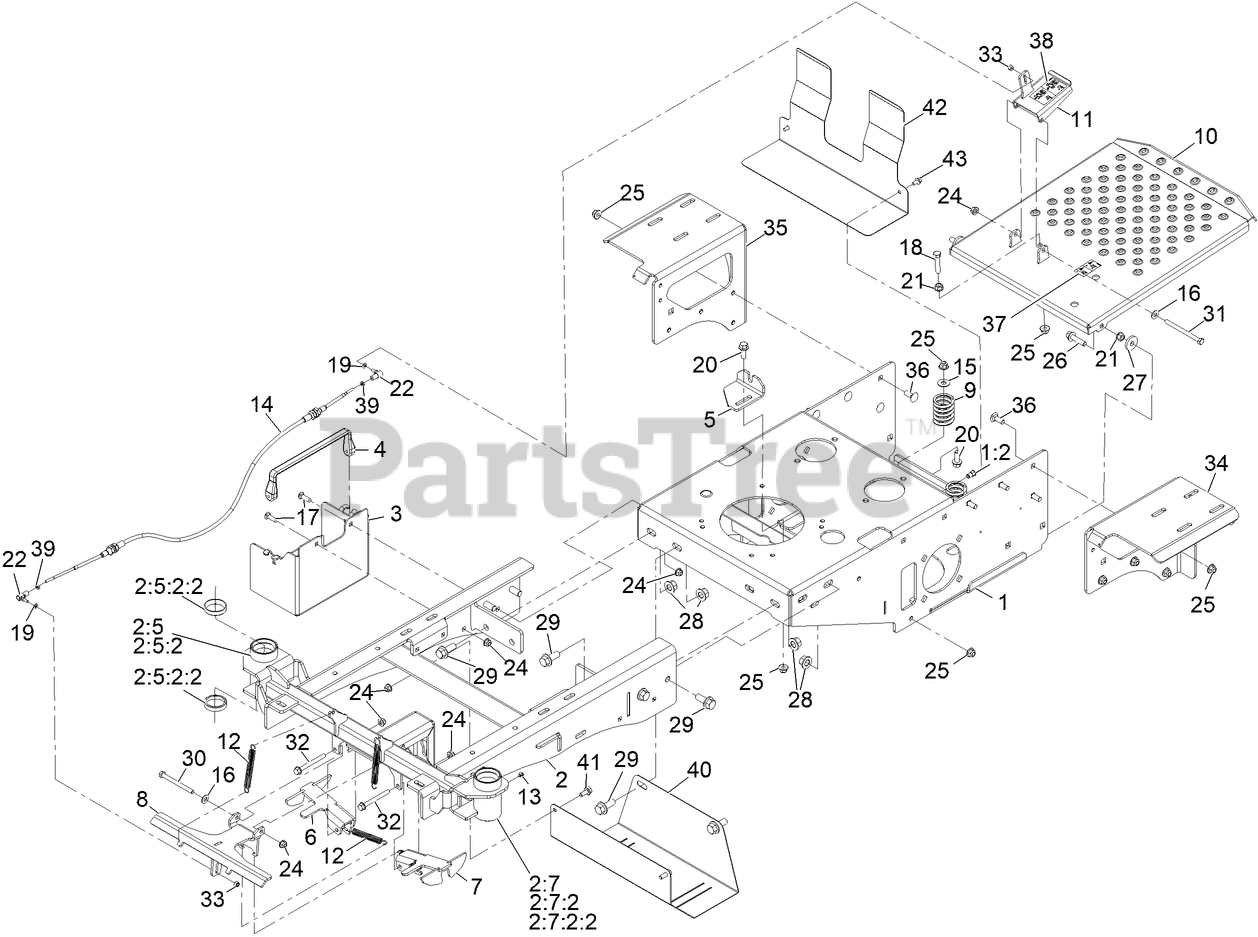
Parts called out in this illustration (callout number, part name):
1	FRAME-REAR
1:2	NUT-CLINCH,HEX
2	WLD, FRONT FRAME, JR36 24
2:5	Tube-Caster Rt
2:5:2	Tube-Caster, W/Cup
2:5:2:2	BEARING-CUP, TAPERED
2:7	Tube-Caster Lt
2:7:2	Tube-Caster, W/Cup
2:7:2:2	BEARING-CUP, TAPERED
3	BOX-BATTERY
4	BUNGEE (TARP STRAP)
5	Bracket, Lower Cable
6	Wing-Capture, Rt
7	Wing-Capture, Lt
8	WLD, CAPTURE, T-BAR, JR36
9	SPRING-COMPRESSION
10	WLD, FOOT PLATE, JR36
11	Wld, Foot Pedal, Lcs
12	SPRING-EXTENSION
13	FITTING-GREASE, ZERK
14	CABLE-CASTER, LOCKING
15	WASHER-FLAT
17	Bolt,Carriage,5/16-18X1,ST/ST 18-8
18	Screw-HH
19	WASHER-FLAT
20	SCREW-HHF
21	Nut-Hex Flange
22	BALL JOINT-SS
24	Nut-Hex Flange
25	Nut-Hex Flange
26	SCREW-HHF
28	NUT-HEX FLANGE
29	SCREW-HHF
30	SCREW-HH
31	Screw-HH
32	SCREW-HHF
33	Nut,NYL Lock,#10-32,ST/ST 18-8
34	WLD, MOUNT, FERT BOX, L, JR36
35	WLD, MOUNT, FERT BOX, R,
36	SCREW-CARR
37	Decal-Spray Foot Button
38	Decal-Lock, Caster
39	Nut,Hex Jam Mch Scr,10-32,Sst
40	GUARD, MUFFLER, JR36
41	SCREW-HHF
42	Shield, Heat, HYD Pump, Jr36
43	SCREW-HHF
